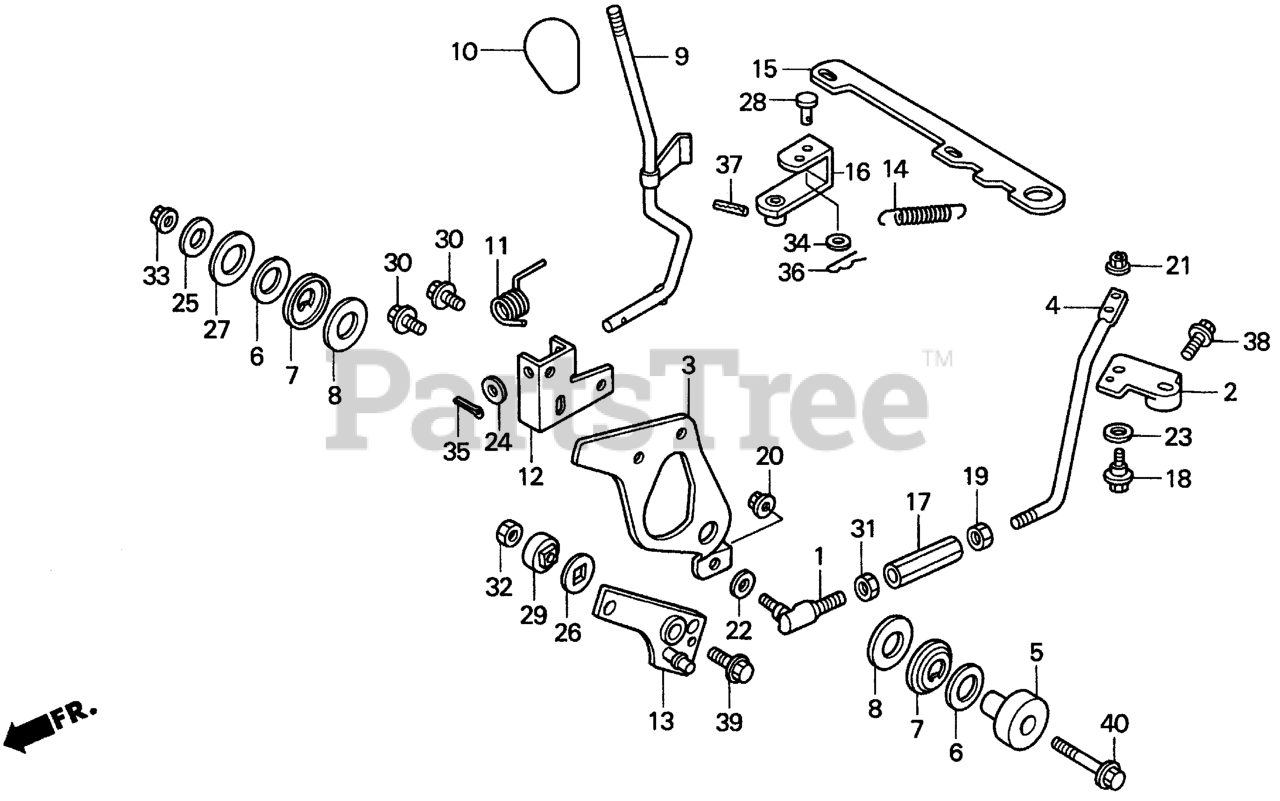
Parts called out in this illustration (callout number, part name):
1	JOINT, R. BALL
2	ARM, CONTROL
3	ARM, CHANGE
4	ROD, GEARSHIFT
5	SHAFT, CHANGE ARM
6	SPRING, FRICTION
7	GUIDE, FRICTION SETTING
8	WASHER, FRICTION
9	LEVER, CHANGE
10	GRIP, CHANGE LEVER
11	SPRING, CHANGE LEVER
12	BRACKET, CHANGE LEVER
13	ARM A, RETURN
14	SPRING, NEUTRAL VALVE LEVER
15	LEVER, NEUTRAL VALVE
16	ARM, NEUTRAL VALVE
17	JOINT (12MM) (3/8")
18	BOLT, SPECIAL
19	NUT, L. HEX. (12MM)
20	NUT, FLANGE (3/8-24)
21	NUT, SELF-LOCK (6MM)
22	WASHER, PLAIN (10MM)
23	WASHER, SPECIAL (10MM)
24	WASHER, SPECIAL
25	WASHER (12.5X33)
26	WASHER, RETURN ARM
27	WASHER, SPRING SETTING
28	PIN, SEAT LOCK
29	BUSH (12.1X23X20)
30	BOLT-WASHER (8X16)
31	NUT, HEX. (3/8-24)
32	NUT, HEX. (12MM)
33	NUT, FLANGE (12MM)
34	WASHER, PLAIN (6MM)
35	PIN, COTTER (4X25)
36	PIN, LOCK (6MM)
37	PIN, SPRING (4X25)
38	BOLT, FLANGE (8X20)
39	BOLT, FLANGE (12X25)
40	BOLT, FLANGE (12X60)
